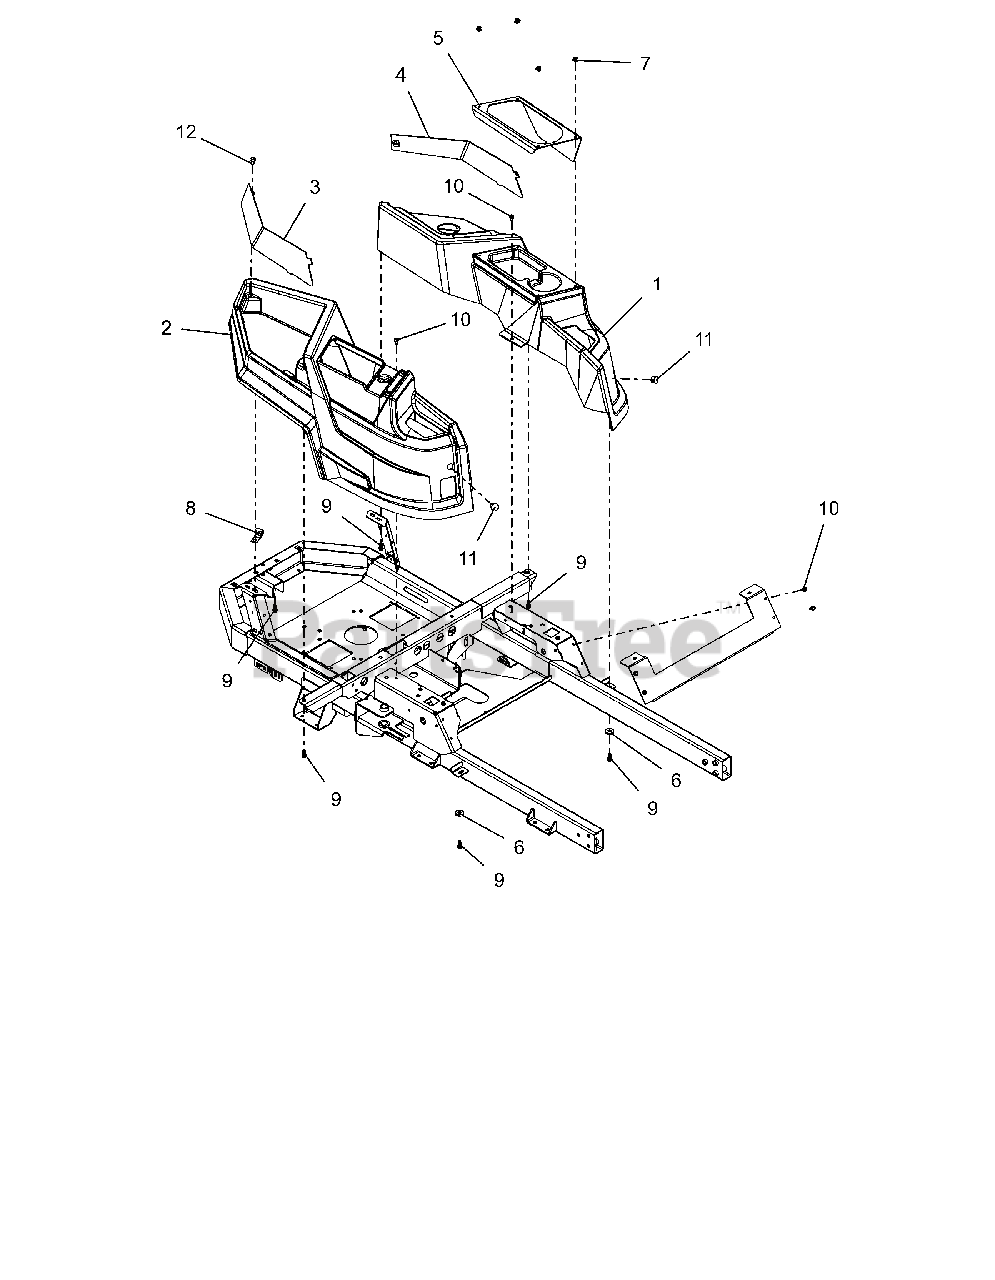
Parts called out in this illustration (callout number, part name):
1	FENDER, LH -ZOOM
2	FENDER, RH -ZOOM
3	WLMT, FENDER BLOCKOFF-RH
4	WLMT, FENDER BLOCKOFF-LH
5	PANEL, CUPHOLDER/STORAGE (LH)
6	WSHR, FLT .406X1.00X.188 ZCC
7	RIVET, PLASTIC .195 DIA.
9	SCR-.312X.75 #14H H/W/H H/L CZ
10	SCR-TAP .25-20X.50 HWH ZCC
11	PLUG, HOLE .75 (BLACK)
12	XMAS TREE FASTNER-BLACK
